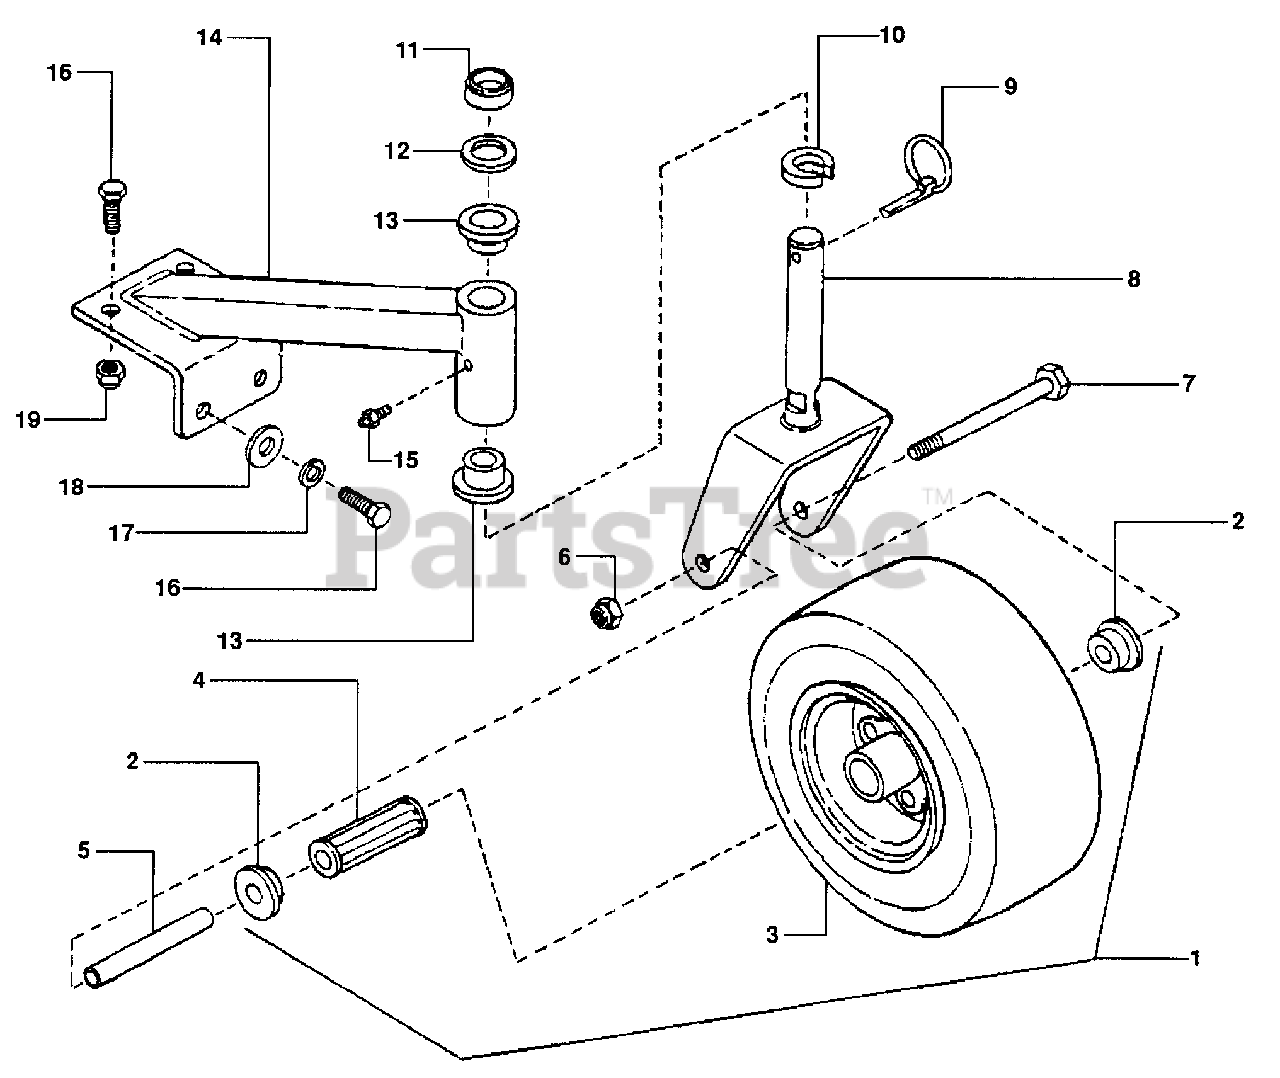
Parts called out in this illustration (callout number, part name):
1	ASSEMBLY, Wheel and Tire
2	RETAINER, Flanged
3	ASSEMBLY, Tire and Rim, 9 x 3.5 Foam-Filled
4	ROLLER BEARING
5	SLEEVE, Axle
6	NUT, 1/2 - 13 Nyloc
7	BOLT, 1/2 - 13 x 5 1/2" HHC
8	YOKE, Caster Weldment
9	PIN, Lynch
10	SPACER
11	SPACER, 1" x 1 3/8 x .30" (PM)
12	SPACER
13	BUSHING, Caster
14	ASSEMBLY, Caster Support
15	FITTING, Lube
16	SCREW, 3/8 - 16 x 1" HHC
17	WASHER, 3/8 Lock
18	WASHER, 3/8" Flat
19	NUT, 3/8 - 16 Nyloc
